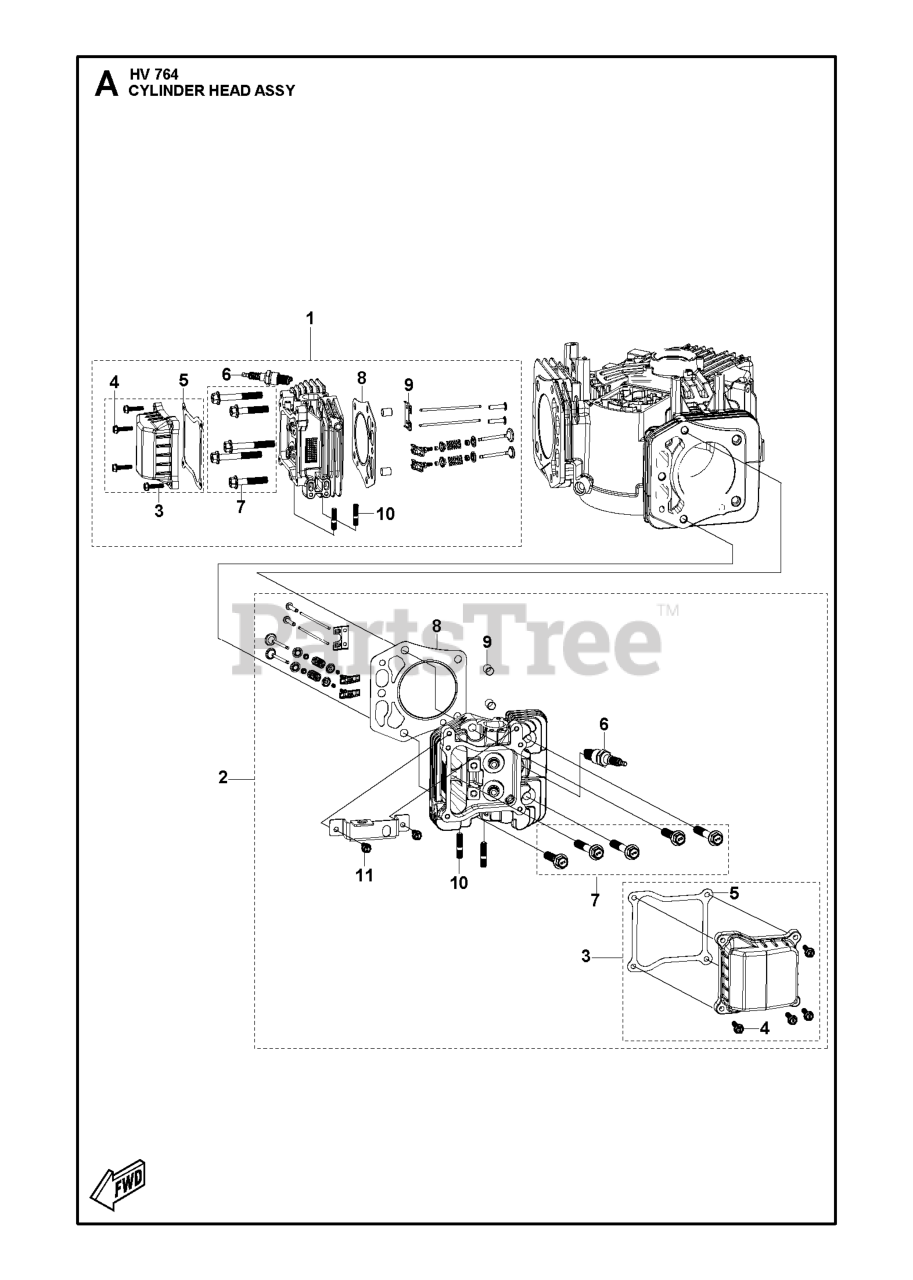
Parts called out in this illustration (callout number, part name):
4	BOLT GB/T 5789: M6 L=25
6	SPARK PLUG HQT-7 RESISTOR
8	Husqvarna TBD
